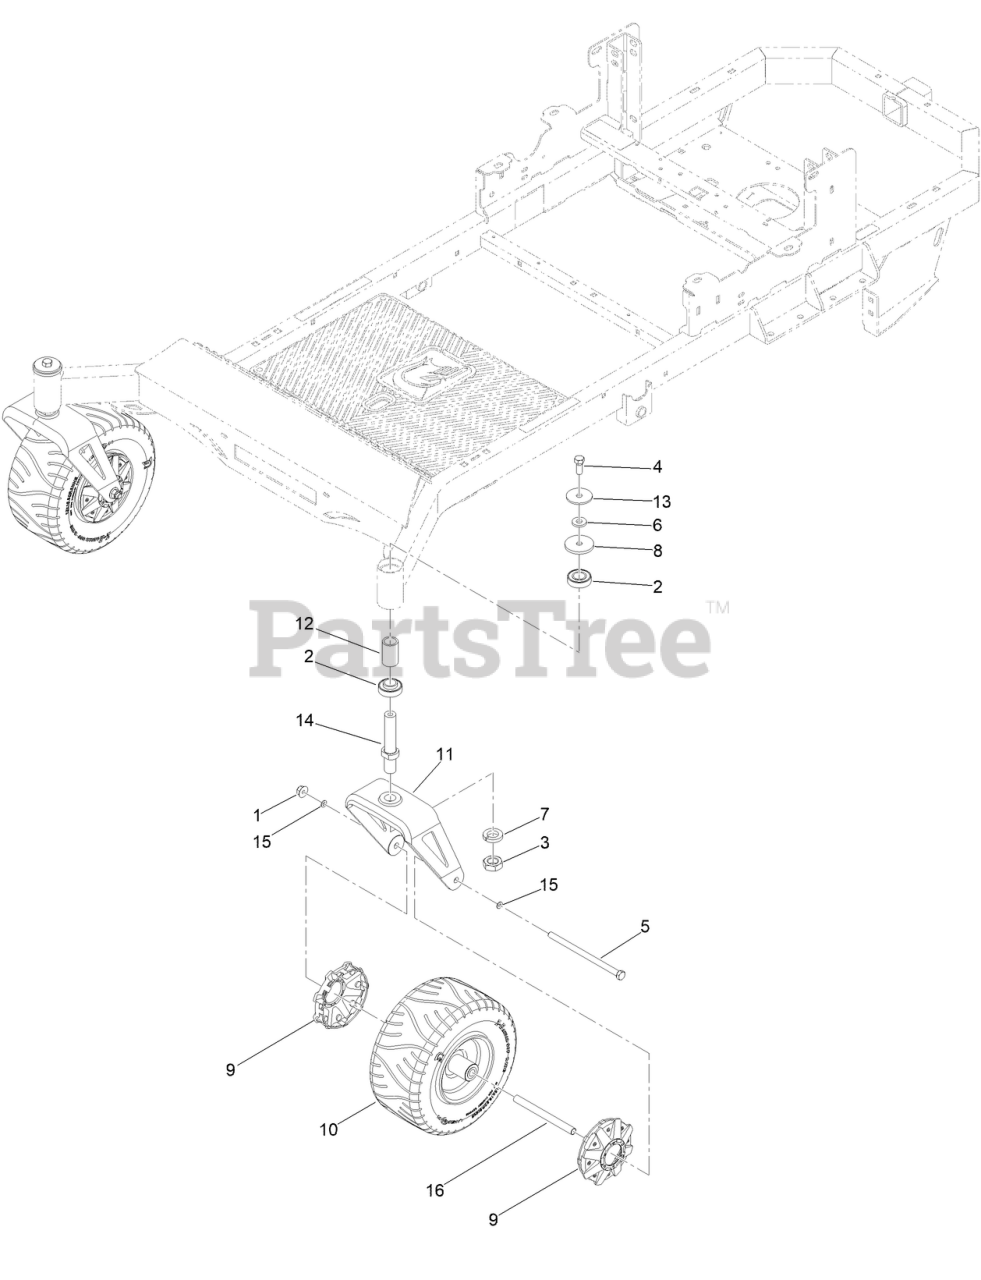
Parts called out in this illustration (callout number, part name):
1	NUT-LOCK
2	BEARING-BALL
4	1/2-20 X 1-1/4 HEX FLANGE BOLT GR 8 YZ
5	1/2-13 X 8-1/2 HEX C/S GR 5 ZINC YELLOW
6	1/2 FENDER WASHER 1-1/4IN OD ZINC
7	1IN L/W MED SPLIT ZC
8	FT HUB PLASTIC WASHER
9	MWR FT WHEEL HUB CAP
10	SPARTAN RADIAL FT TIRE AND WHEEL ASSM
11	RT AND SRT CASTER WHEEL FORK
12	CASTER FORK SHAFT BEARING SPACER
13	MWR CASTER SHAFT WASHER
14	MWR CASTER SHAFT
15	WASHER-FLAT
16	MWR FT WHEEL SPANNER
